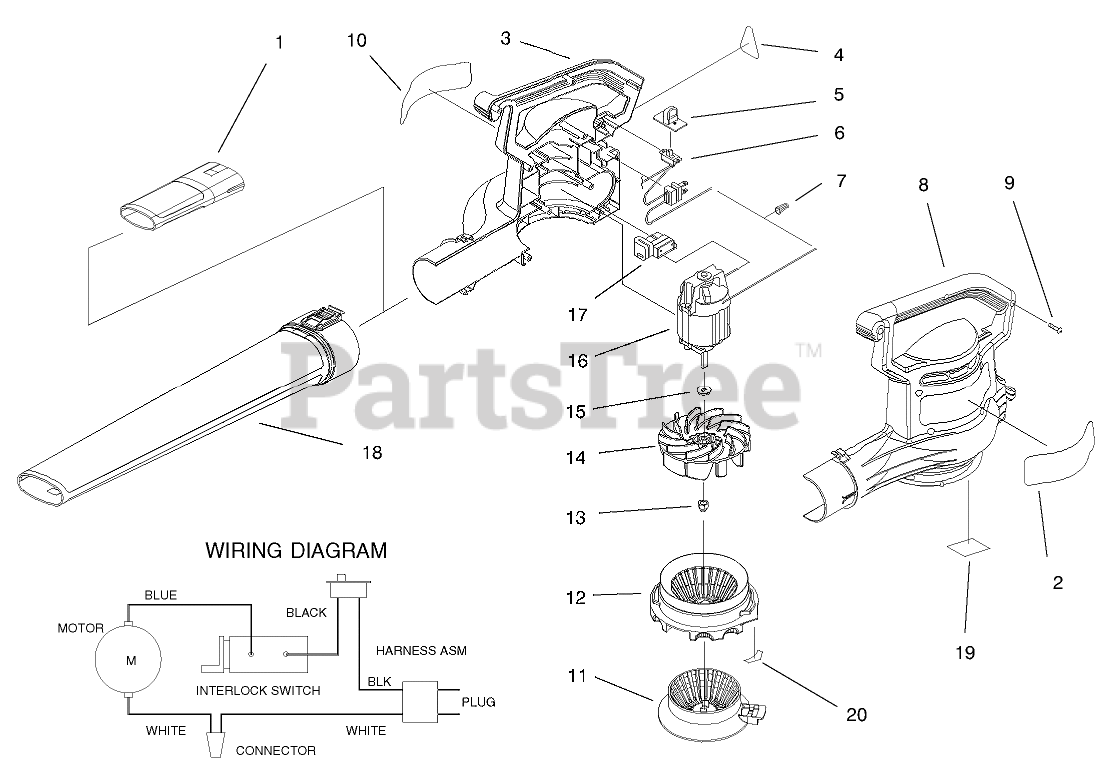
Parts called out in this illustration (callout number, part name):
1	INSERT - TUBE
2	DECAL, LOGO, SUPRBLWR
3	Housing-R.H.
4	DECAL - INFORMATION
5	COVER - SWITCH, RED
6	HARNESS ASSEMBLY
7	CONNECTOR-NUT, WIRE
8	Housing-L.H.
9	SCREW-PPH
10	DECAL-SERIAL, SUPERBLOWER
11	CHOKE - AIR, RED
12	Cover-Inlet
13	NUT-HEX
14	IMPELLER - BLOWER
15	WASHER
16	MOTOR - ELECTRIC, 120 V
17	SWITCH - INTERLOCK
18	TUBE-BLOWER LONG
19	DECAL-ALIGNMENT, HOUSING
20	DECAL-ALIGNMENT, COVER
